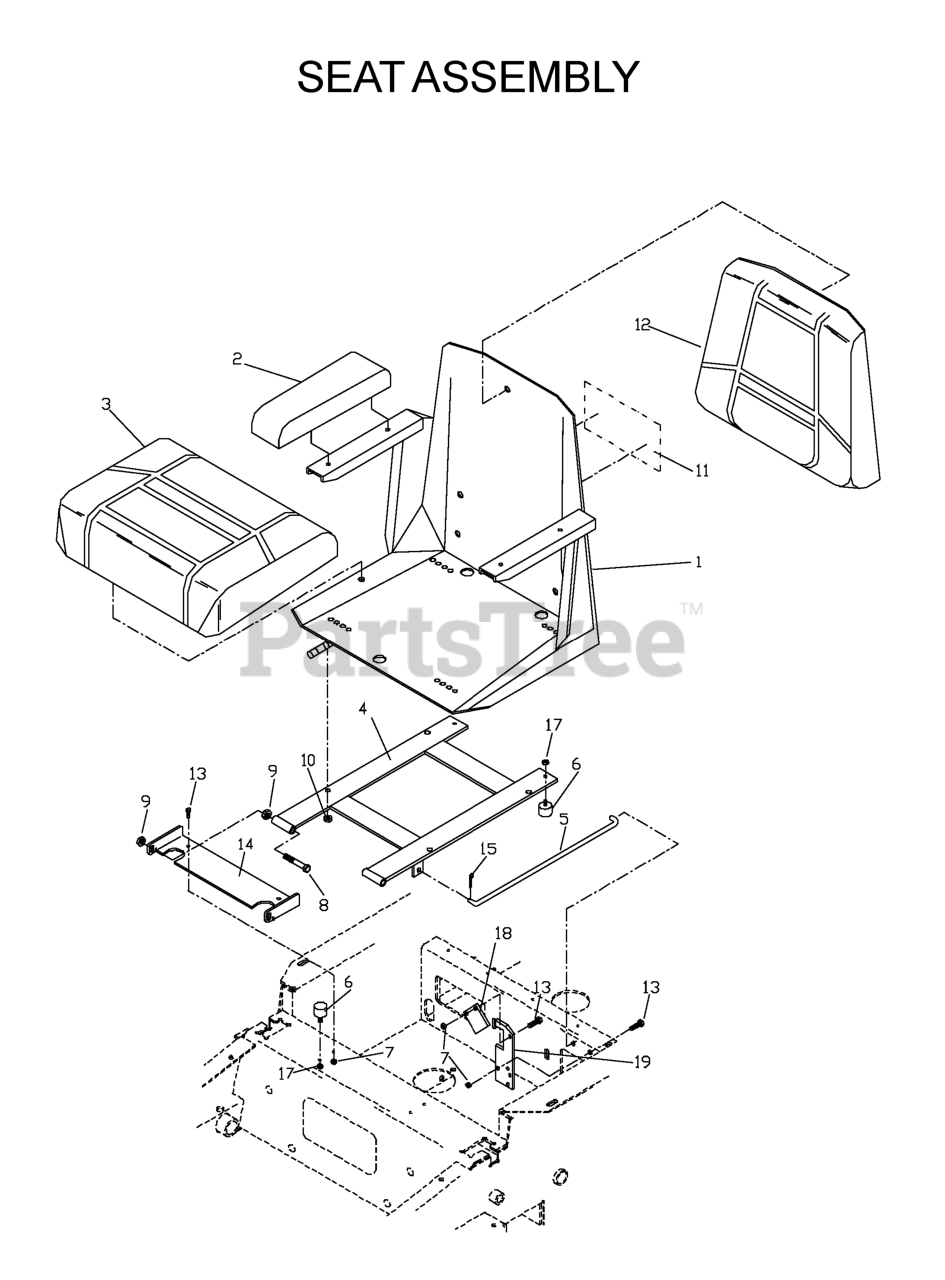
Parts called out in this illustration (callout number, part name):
1	SEAT, COMPLETE
2	ARM REST CUSHIONS/PAIR
3	SEAT CUSHION W/SWITCH
4	SEAT MOUNT W/DECAL
6	STUD/PLATE MOUNT
7	NUT 1/4C CENTERLOCK
8	HCS 3/8C X 3
9	NUT 3/8C CENTERBLOCK
10	NUT 5/16C CENTERLOCK
11	DECAL, HUSQVARNA LOGO 9.25"
12	SEAT, BACK CUSHION
13	HCS 1/4C X 3/4 HCS
15	RP_COTTER PIN 1/8 X 3/4
16	SEAT RAILS
17	NUT.1/4-20.HEX.NYLOC.ZD
18	SEAT LATCH
19	SEAT LATCH BASE
